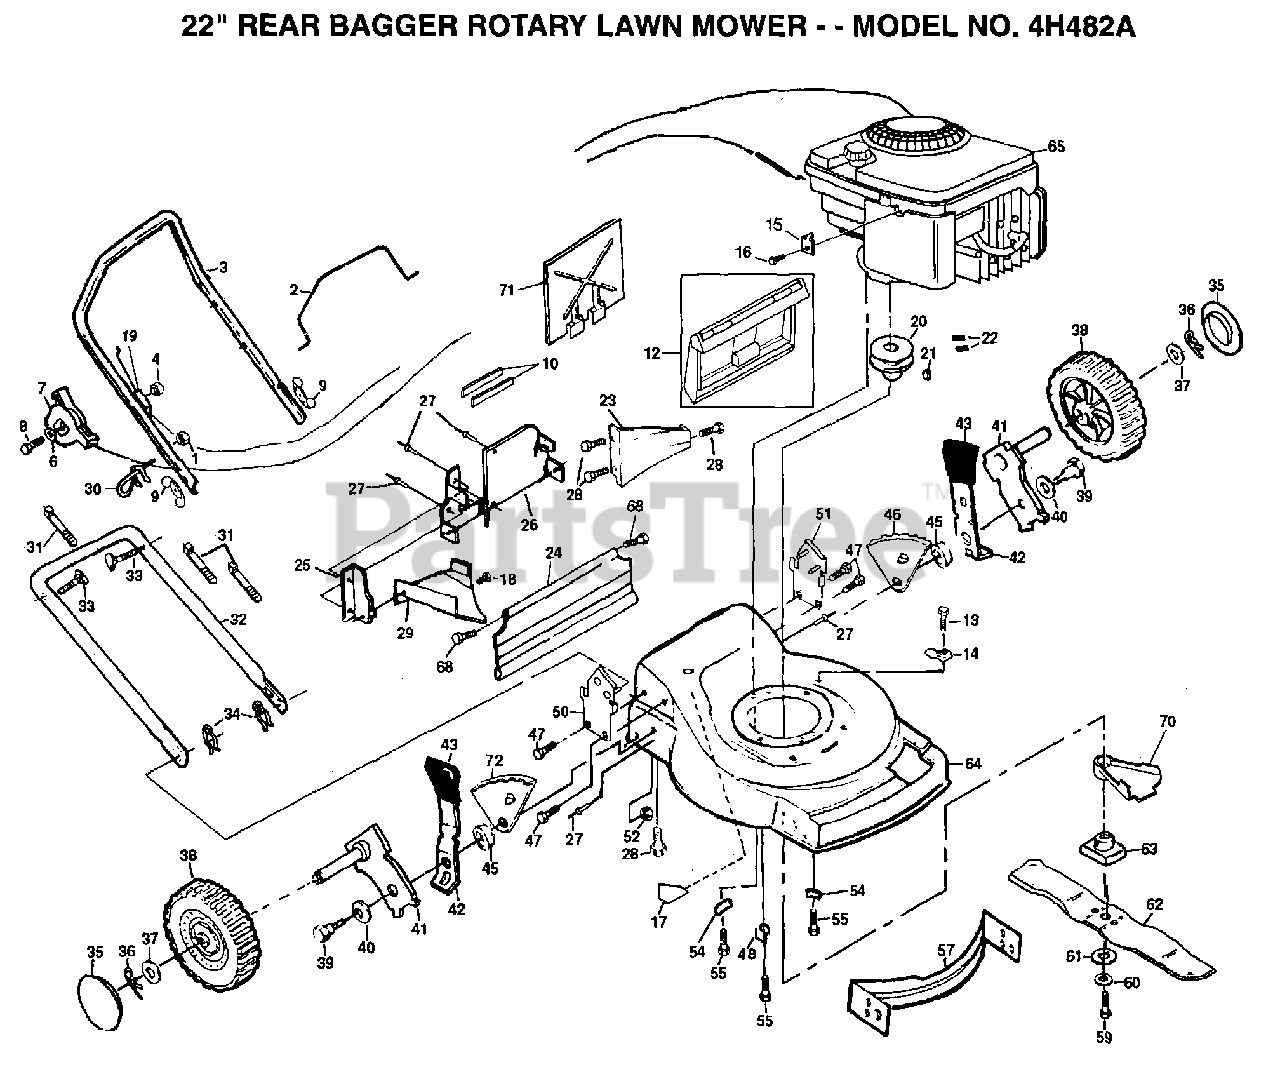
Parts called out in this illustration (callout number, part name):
1	NUT
2	"BAR,CONT"
6	WASHER PM
7	"CONTROL, THROTTLE"
9	"NUT,WING PM"
10	"SEAL,REAR DOOR"
13	TAPPING SCREW
14	GUIDE CLIP PM
15	CABLE CLAMP
16	SCREW PM
17	DECAL HYT
18	SCREW PM
19	"CABLE,ENG ZONE CO"
20	ENGINE.PULLEY.FWG
21	HI PRO KEY PM
22	SCREW
23	REAR BAFFLE
26	PLATE.BACK
27	BLIND RIVET
28	SCREW
29	DISCHARGE BAFFLE
30	ROPE GUIDE
33	BOLT.HANDLE.LM
34	HAIRPIN COTTER
35	HUB CAP
36	RETAINER CLIP PM
37	WASHER
40	"WASHER, BELLEVIL."
41	AXLE ARM
42	SPRING SELECTOR
43	KNOB PM
47	SCREW
48	DEBRIS SHLD RET
52	LOCKNUT PM
55	SCREW
59	SCREW
60	LOCKWASHER
61	"WASHER,HARDEN"
63	ADAPTOR.BLADE.LM
64	KIT.HSG.22RD.FWGD
68	HINGE SCREW
71	MULCHER PLATE
